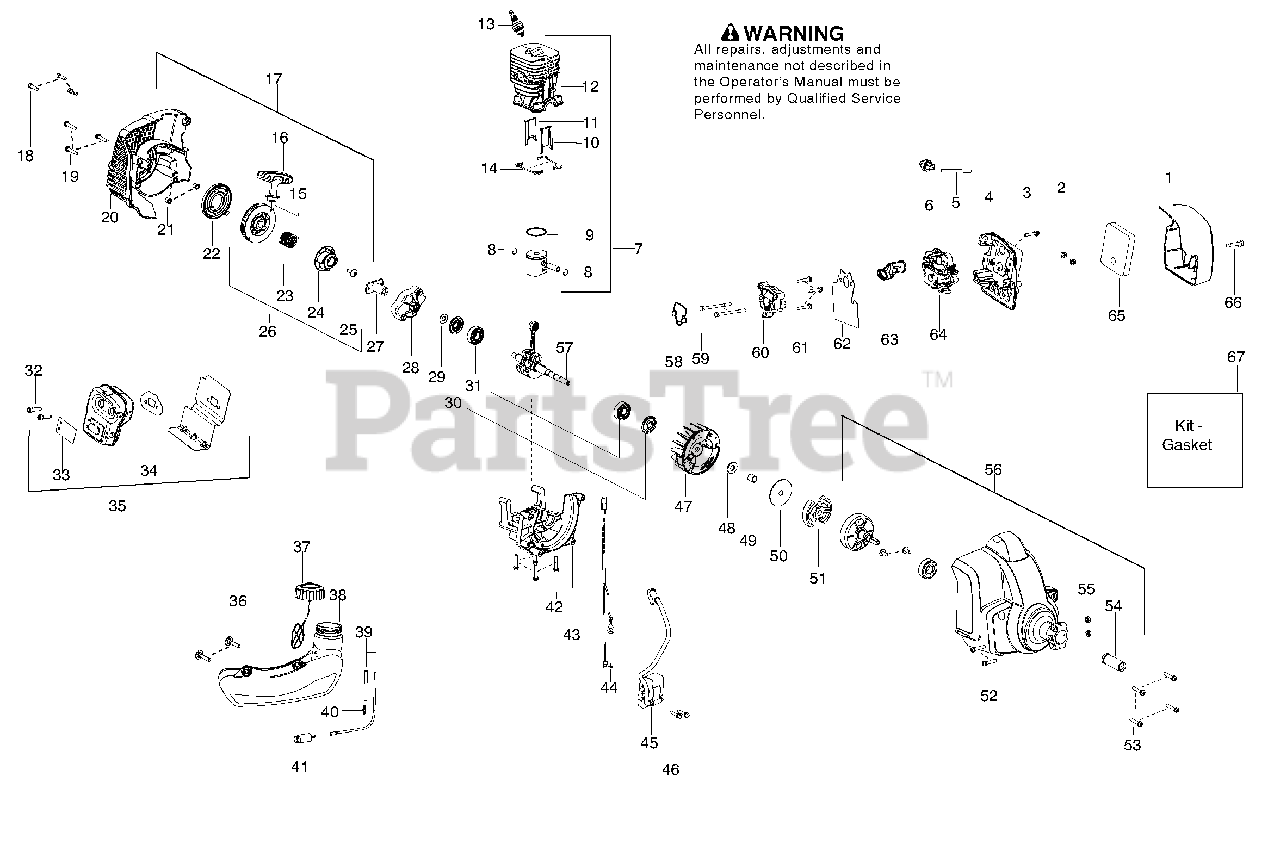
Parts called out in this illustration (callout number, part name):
1	Cover - Airbox
2	Nut - Carb. Screw
4	Base - Airbox
6	Assy - Purge Bulb
7	Kit - Piston/Cylinder
8	Retainer - Piston pin
9	Ring - Piston
10	Insert - Front Transfer Port
11	Insert - Rear Transfer Port
12	Cylinder - Machined
13	Spark Plug (RCJ- 6Y)
14	Seal - Cylinder (Kit)
16	Handle - Starter
17	Assy - Starter/Shroud
18	Screw M4 x 1.75
19	Screw m5x25mm
20	Assy - Starter Hsg. w/eyelet
22	Kit - Starter Spring
23	Spring - Starter Hub
24	Hub - Starter
26	Kit - Starter Pulley
27	Coupling - Starter
28	Assy - Starter Cup
29	Washer - Flat
30	Seal - Crankshaft (kit)
31	Bearing - Crankshaft
32	Bolt - Muffler
33	Kit - Spark Arrestor
34	Gasket - Muffler (kit)
35	Assy - Muffler
36	Screw - Tank Retainer
37	Assy - Fuel Cap w/ret.
38	Assy - Tank
39	Kit - Fuel line
40	Fitting - Fuel Line
41	Assy - Fuel Pickup
42	Screw - m5x25mm
44	Assy - Leadwire
45	Module - Ignition
49	Spacer - Flywheel
50	Washer - Clutch
51	Kit - Clutch Assy.
52	Screw 10-24 x 1"
53	Screw M5 x 25mm
54	Guide - Clutch Drum
55	Locknut 10-24
56	Assy - Fan Housing
57	Kit - Crankshaft Assy.
58	Seal - Cyl./Adapter (kit)
59	Bolt M5 x .80
60	Adaptor - Carburetor
61	Screw .20 x 32
62	Gasket - Carb./Adapter (kit)
64	Kit - Carburetor
67	Kit - Gasket
